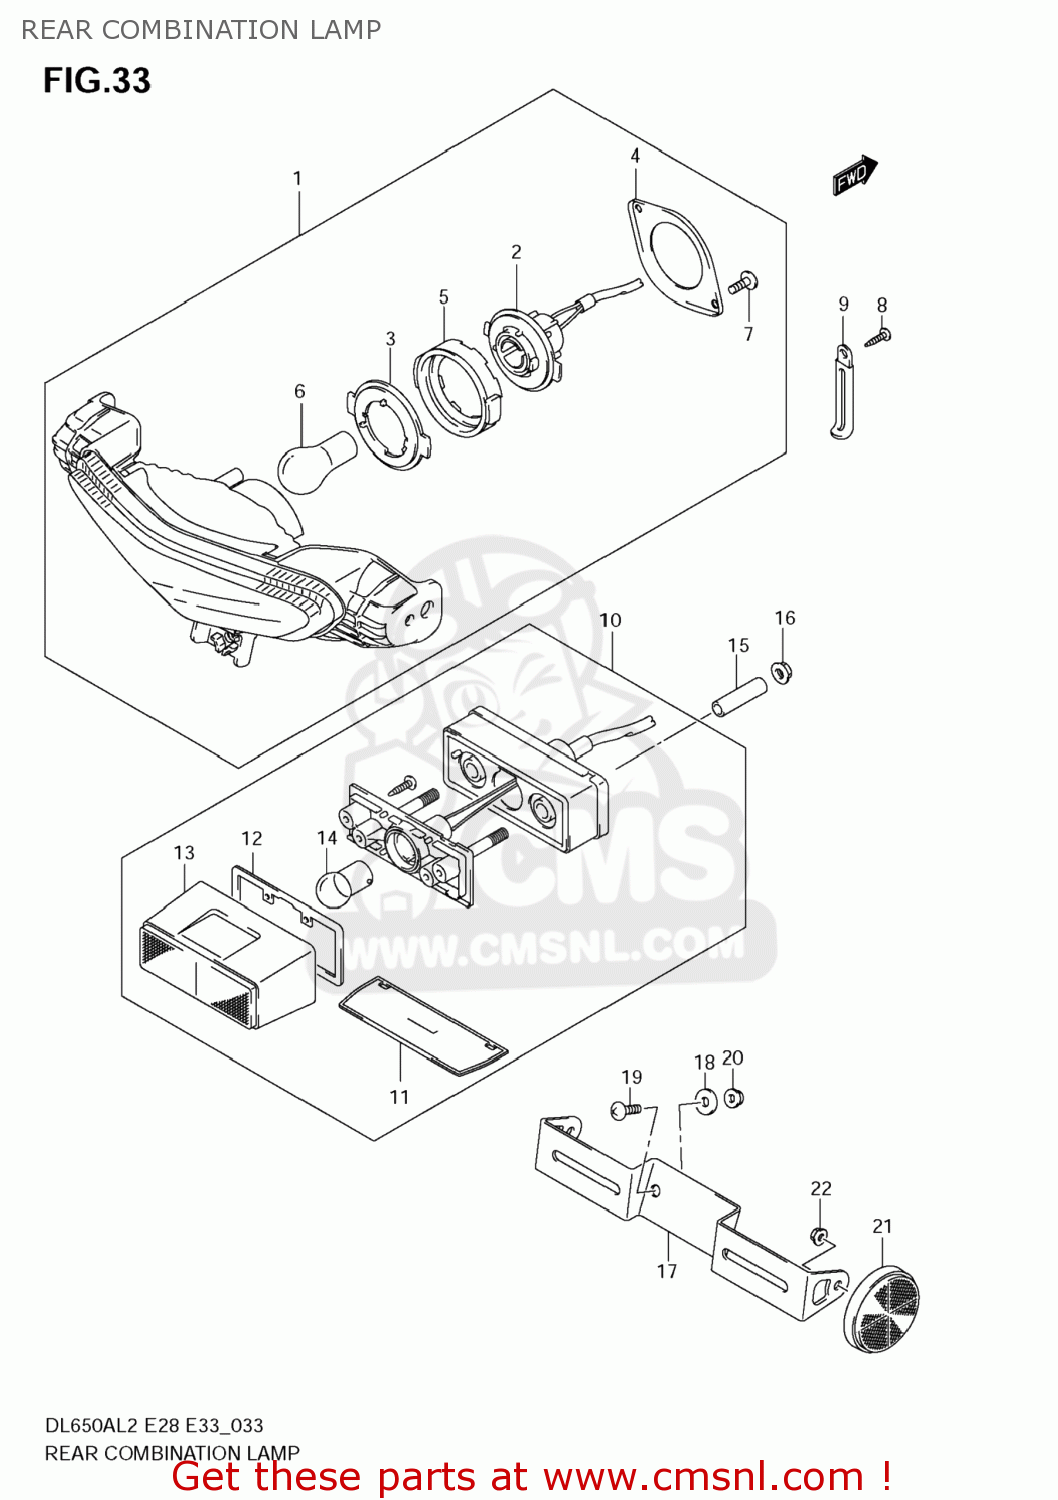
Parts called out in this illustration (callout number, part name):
1	LAMP ASSY,RR COMBINATION
2	SOCKET & CORD
3	PLATE NO.1
4	PLATE NO.2
5	CUSHION
6	BULB(12V21/5W)
7	SCREW
8	SCREW
9	CLAMP(L:45)
10	LAMP ASSY,LICENSE
11	LENS,LICENSE LAMP
12	GASKET (NAS)
13	COVER,LICENSE LAMP
14	BULB(12V5W,BF150-40160A)
15	SPACER(6.5X9X33.3)
16	NUT
17	BRACKET,LICENSE PLATE
18	WASHER(6.5X20X1.2)
19	SCREW
20	NUT
21	REFLECTOR ASSY,RR SIDE
22	NUT
